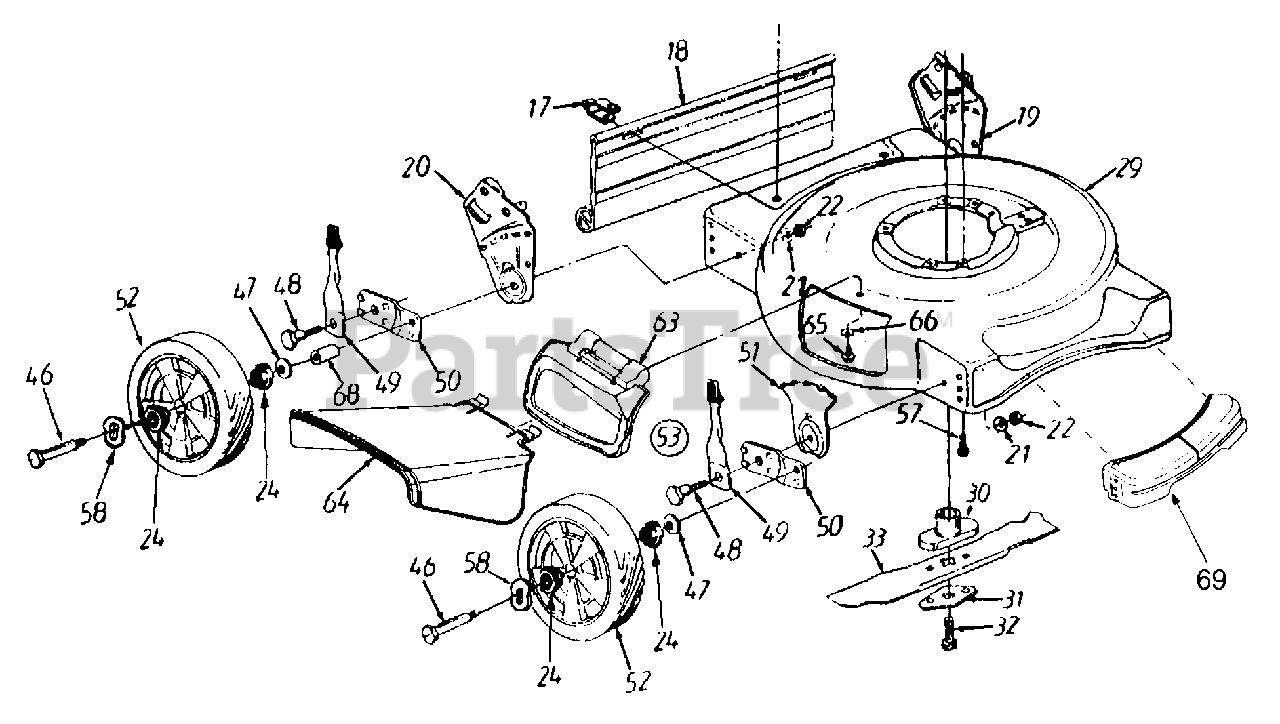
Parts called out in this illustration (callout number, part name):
17	Hinge Clip
18	Rear Flap
21	Bell Washer .39" ID x 1.38"
22	Hex Nut 3/8-16 Thd.
24	Bearing
29	Deck Assembly
30	Blade Adapter Kit
31	Blade Bell Support
32	Hex Bolt 7/16-20 x 1.5"
33	20" Mulch Blade
46	Axle Bolt
47	Bell Washer .400" ID x .88"
48	Shoulder Bolt
49	Spring Lever Assy. w/ Knob
51	Height Adj. Plate
52	Wheel Assembly
53	Height Adj. Ass'y. Comp. R.F.
57	Hex L-Wash. Hd. Scr.3/8-16 x 1.0"
58	Wave Washer
63	Mulching Plug
64	Chute Deflector
65	Hex Wash. Hd. TT Scr. 1/4-20 x .5"
66	Bell Washer
66	Hex Wash. Hd. TT Scr. 1/4-20 x .5"
69	Cover: Front End
